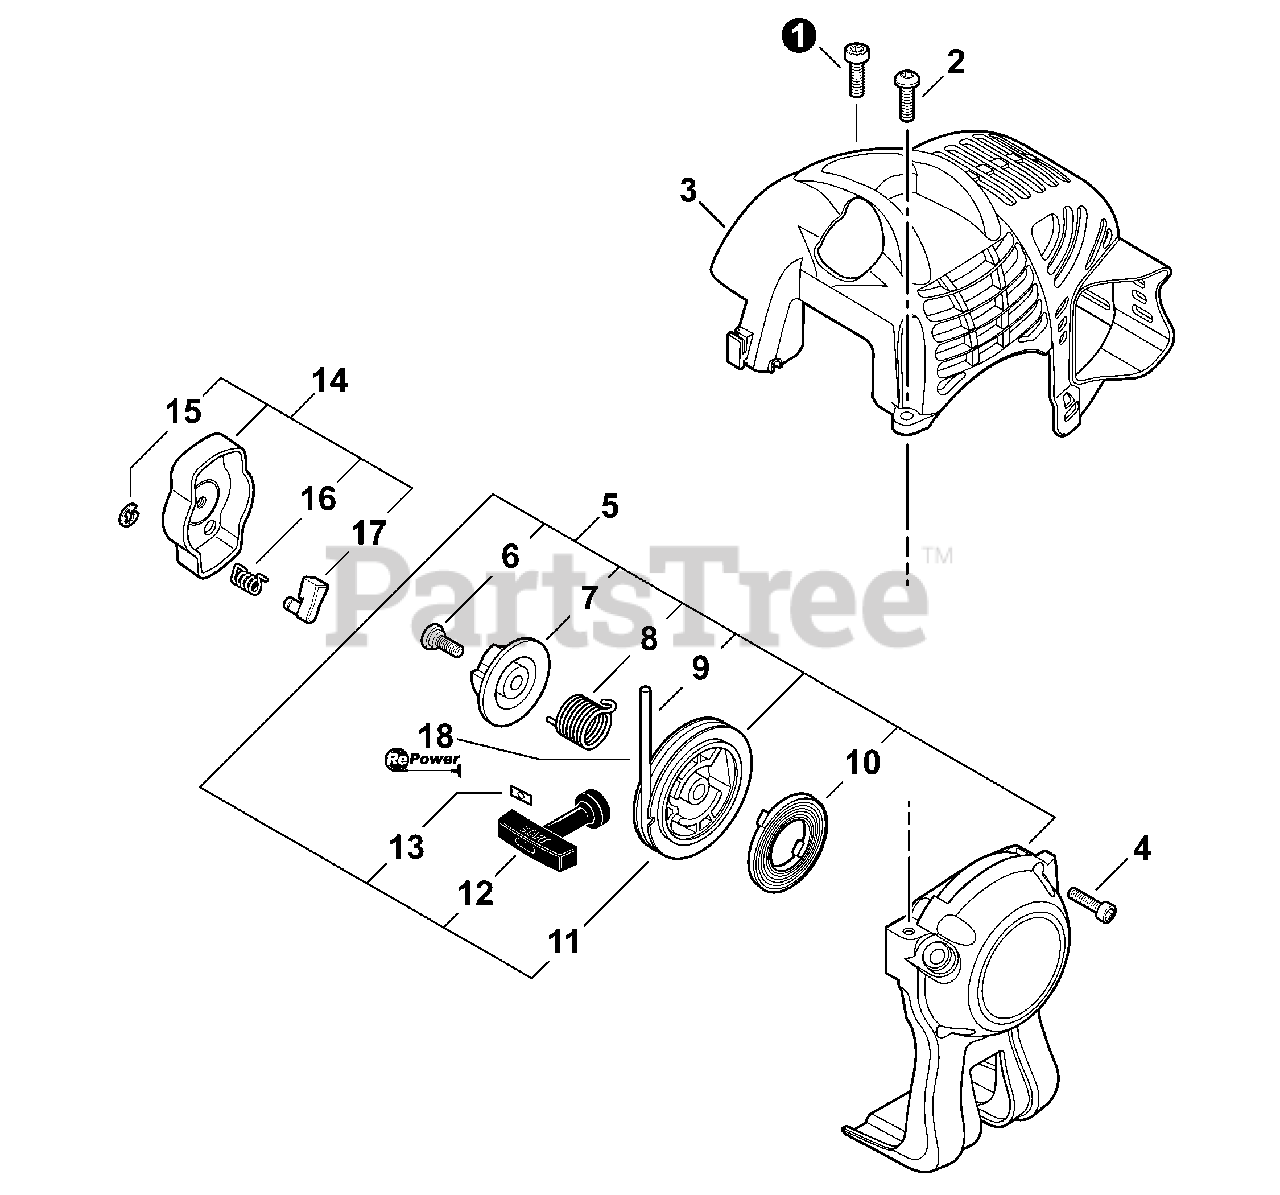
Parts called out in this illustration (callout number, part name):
1	BOLT, TORX 5×16
2	BOLT, TORX 5×16
3	COVER, ENGINE
4	BOLT, TORX 4×16
5	STARTER ASSY, RECOIL
6	SCREW
7	PLATE, CAM (NLA SEE PB 15-06)
8	SPRING, TORSION
9	ROPE, STARTER
10	SPRING, RECOIL
11	REEL, ROPE
12	GRIP, STARTER
13	RETAINER, ROPE
14	PAWL ASSY, STARTER
15	E-RING 4
16	SPRING, RETURN
17	PAWL, STARTER
18	BULK STARTER ROPE - Ø 3.0 MM×61 M
